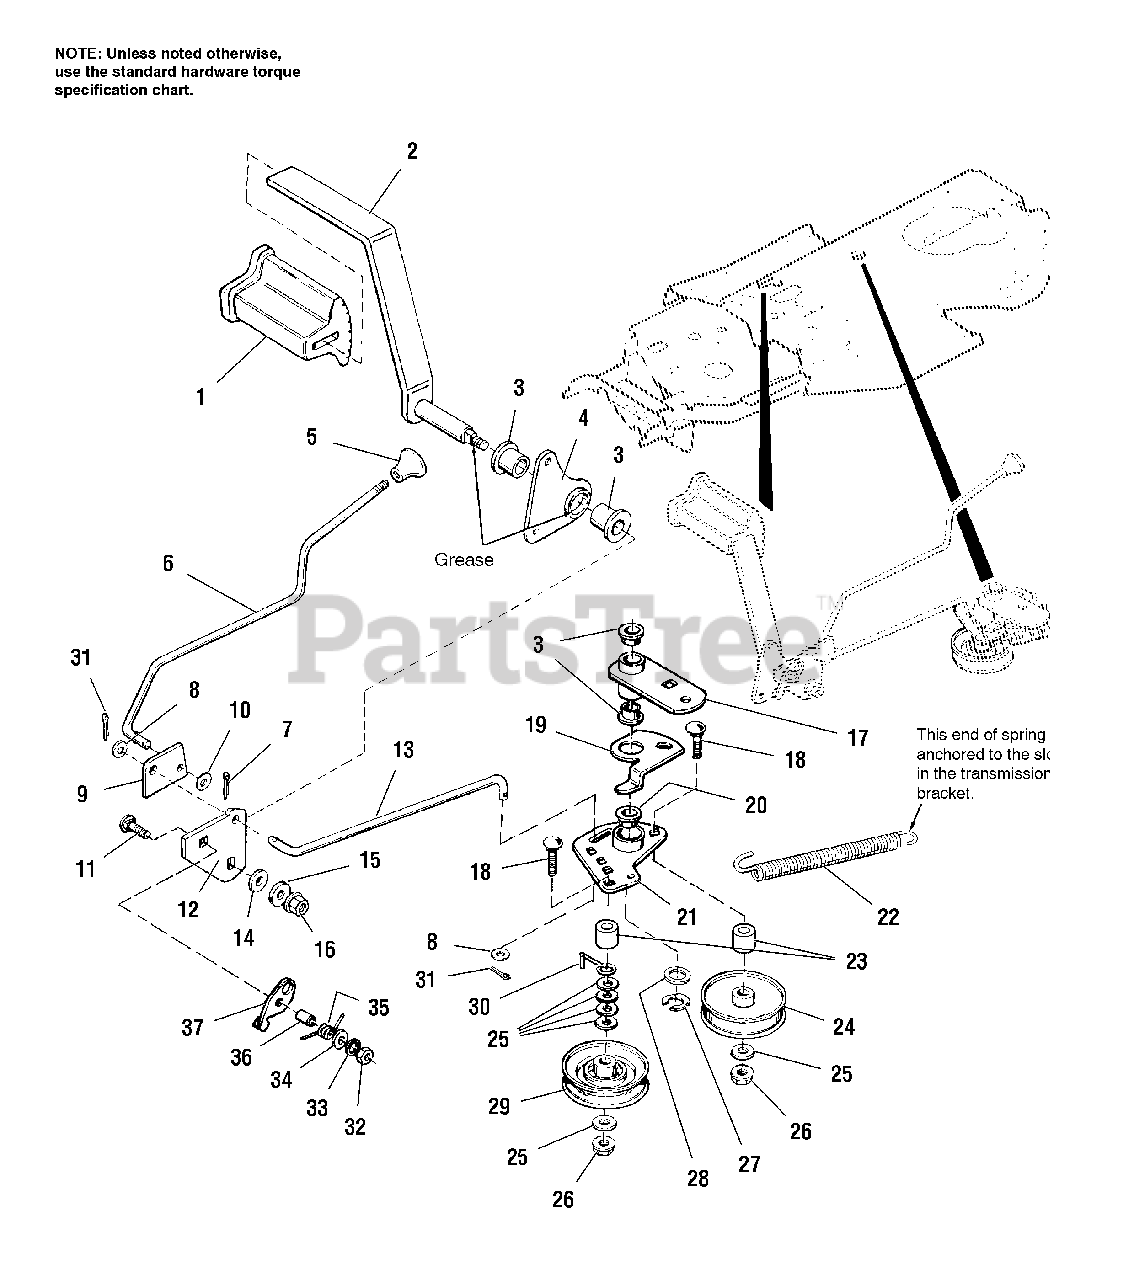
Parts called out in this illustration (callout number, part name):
1	PAD, Foot Pedal
2	BRAKE PEDAL ASSY.
3	BUSHING, Plastic
5	KNOB, Plastic
6	ROD, Parking Brake
7	COTTER PIN
8	WASHER, Plain, 5/16
9	CAM, Parking Brake
10	WASHER, Plain, 9/32
11	CARRIAGE BOLT, 5/16-18 x 1-1/4
12	ARM, Foot Pedal
13	ROD, Clutch, 5/16 Dia.
14	WASHER
15	WASHER, 13/32 x 1-1/2 x 1/16
16	NUT, Hex , Esna, 3/8-16
17	PIVOT ASSY., Shift
18	CAPSCREW, 3/8-16 x 1-3/4
19	LEVER, Lockout
20	BUSHING, Plastic
21	IDLER ARM ASSY.
22	SPRING, Drive
24	PULLEY, Idler, Flat
25	WASHER, Plain, 13/32
26	NUT, Flange, Whizlock, 3/8-16
27	KLIP RING, 5/8
28	WASHER, 5/8
29	PULLEY, "V"
31	COTTER PIN
32	NUT, Hex, 5/16-18
33	LOCKWASHER, 5/16
34	WASHER, 5/8
35	SPRING, Extension
37	ACTUATOR, Switch
